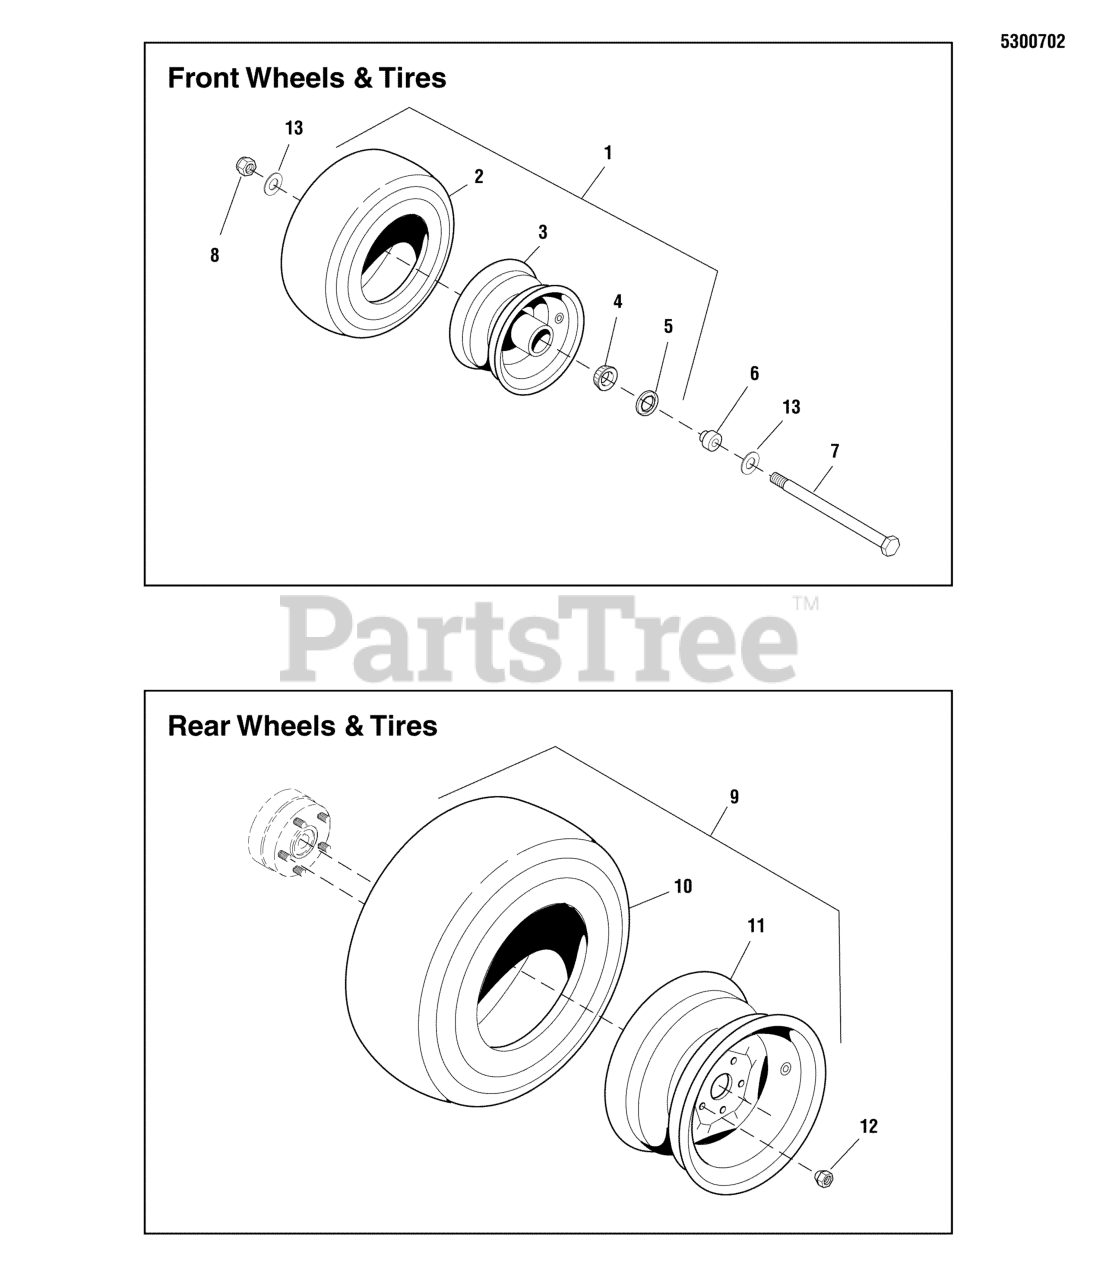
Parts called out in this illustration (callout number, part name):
1	TIRE, CASTER, 13 X 5.00-6
1	* FLAT-FREE TIRE ASSEMBLY, 13 x 5.0 - 6
2	TIRE, 13 x 5.0 - 6
3	WHEEL ASSEMBLY, for 13 x 5.0 - 6 Tire, Complete
4	BEARING, Tapered Roller
5	SEAL, GREASE
6	ADAPTER, CASTER AXLE, CZ
7	BOLT, 1/2-13 X 8" GD5 YZ
8	NUT, Hex Flange, Nylock, 1/2-13
9	TIRE ASSM, 22 X 10.00-10
10	TIRE, 22 X 10.0 -10
11	RIM-10X7-5-4.5 SOLID
12	NUT, 1/2-20, FOR WHEEL BOLT SILVER
13	WASHER, 1/2 SAE
